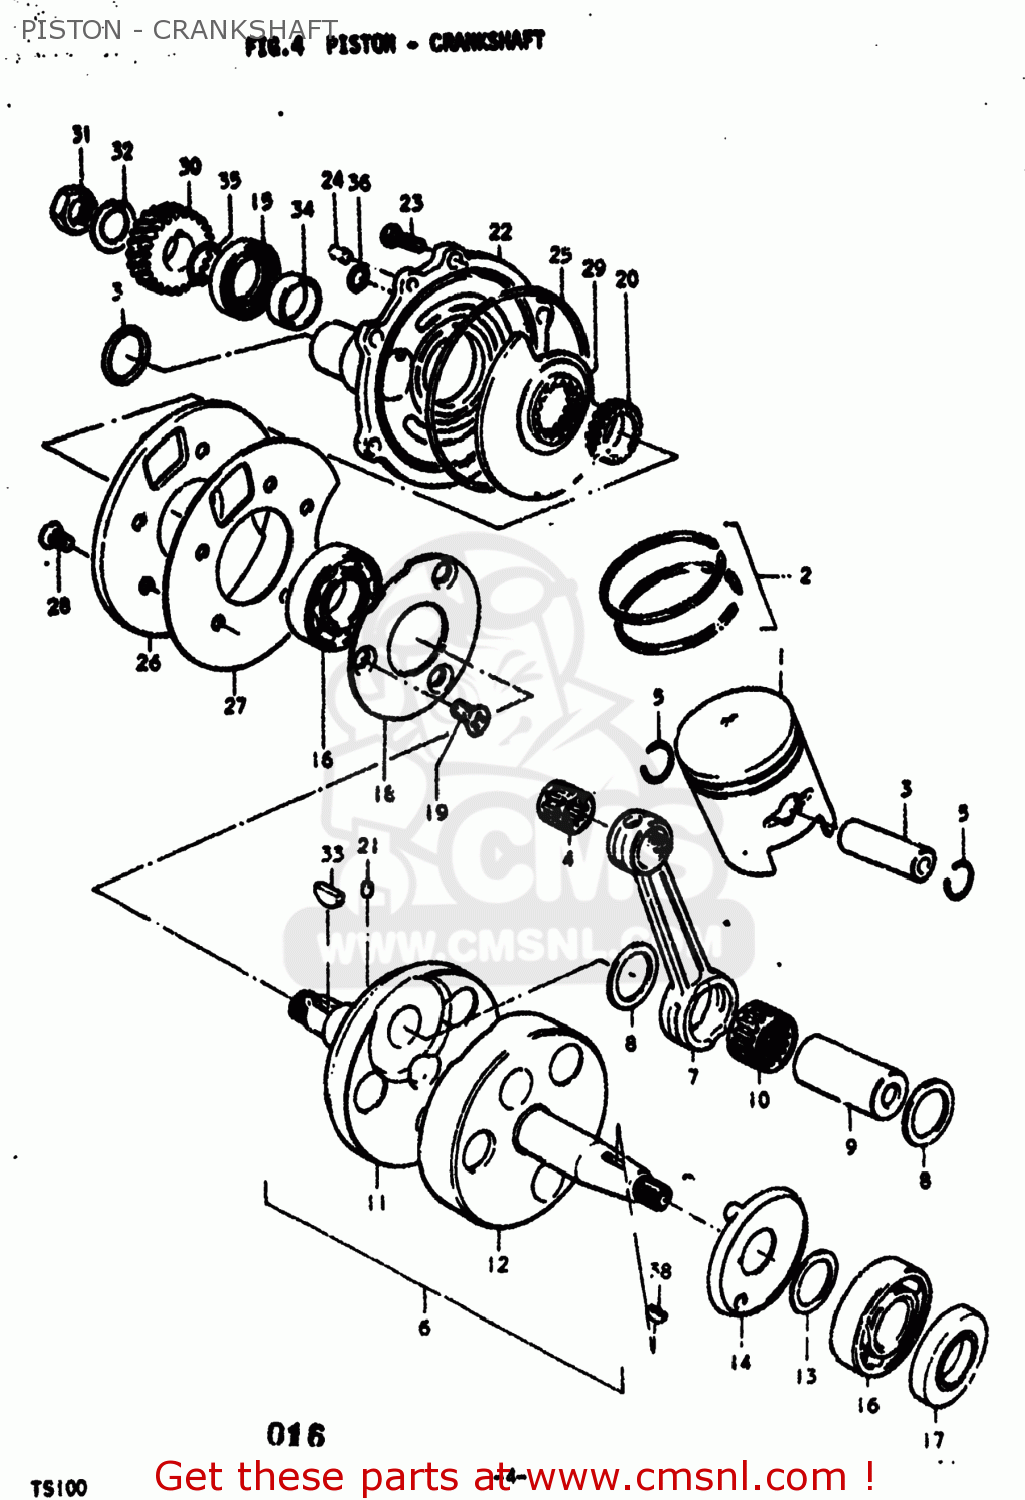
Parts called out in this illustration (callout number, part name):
1	PISTON SET(OS:1.0)
2	RING SET,PISTON
3	PIN,PISTON
4	BEARING
5	RING,SNAP
6	CRANKSHAFT ASSEMBLY
7	ROD,CONNECTING
8	WASHER
9	PIN,CRANK
10	BEARING
11	CRANKSHAFT
12	CRANKSHAFT,LEFT
13	THRUST WASHER
14	PLATE,CRANKSHAFT OIL GUIDE
15	SEAL,OIL(25X40X7)
16	BEARING
17	SEAL,OIL(20X40X7)
18	PLATE
19	SCREW
20	GUIDE,ROTERY VALVE
21	PIN 3X5
22	SEAT,CRANKCASE OUTER VALVE
23	SCREW
24	PIN
25	O RING(D:2,ID:99)
26	SEAT,INNER DISC VALVE
27	GASKET,INNER DISC VALVE (NAS)
28	SCREW
29	VALVE,CRANKSHAFT
30	GEAR,PRIMARY DRIVE
31	NUT
32	WASHER
33	KEY 4MM
34	SPACER
35	O-RING
36	O RING(D:2.5,ID:7.5)
37	O RING(D:3.5,ID:25.7)
38	KEY
